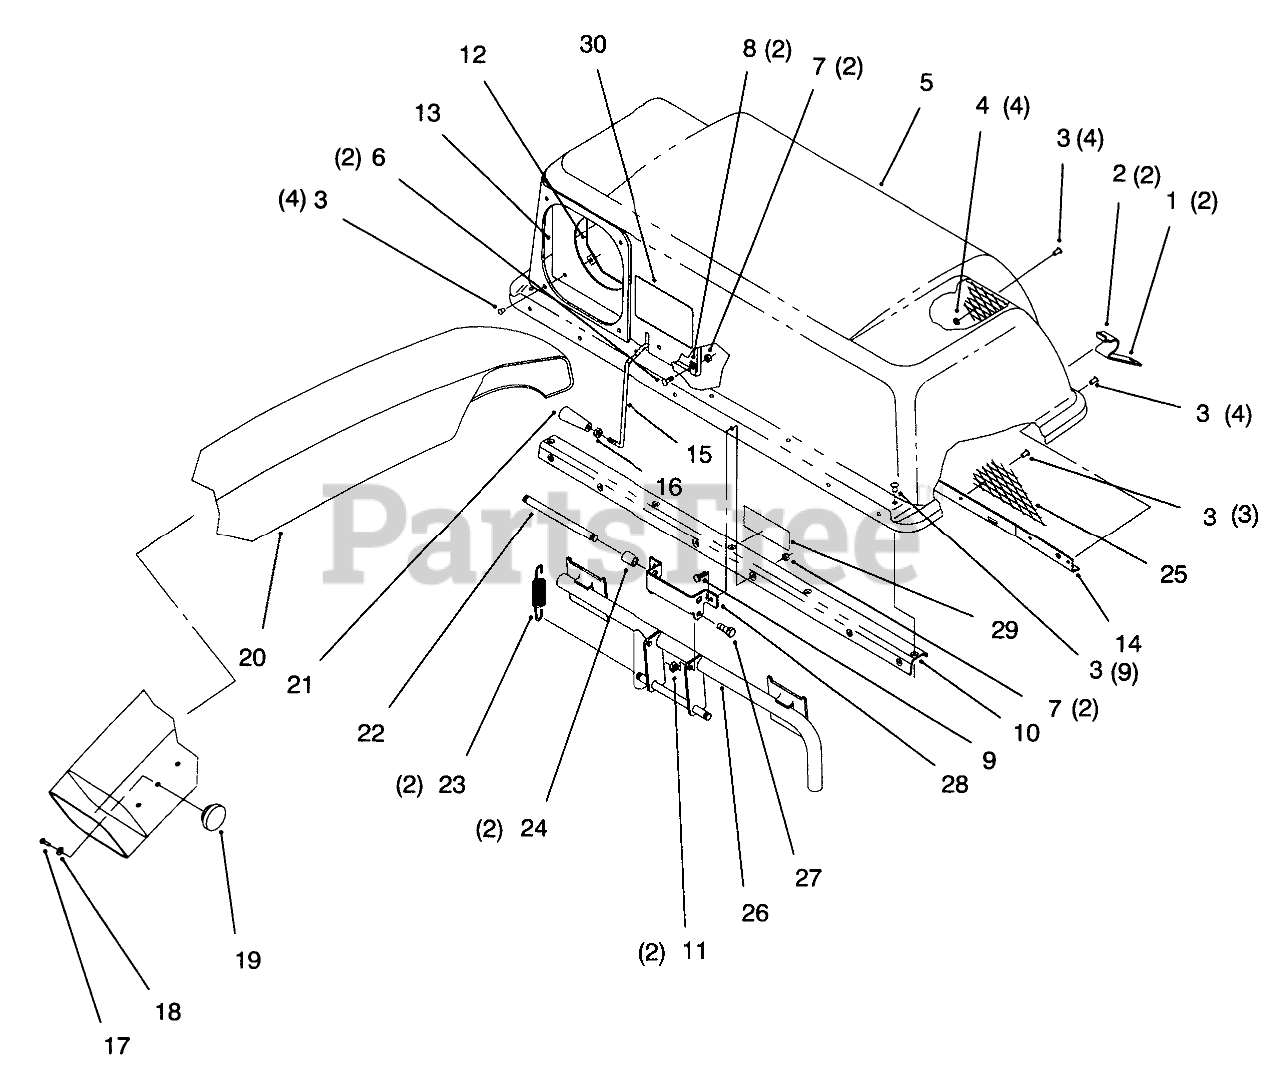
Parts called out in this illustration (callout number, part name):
2	Latch-Bag
3	RIVET-BLIND
4	WASHER-FLAT
5	TOP-BAGGER
6	SCREW-HH
7	NUT-LOCK, NI
8	CLAMP
9	SCREW-HH
10	ASM-Stiffener (Incl. Ref. #29)
11	NUT-LOCK, NI
12	CLAMP-SEAL
13	SEAL-CHUTE
14	Screen Support
15	FEELER-FILL, BAG
16	NUT-JAM
17	SCREW-PPHTF
18	WASHER-PLAIN
20	CHUTE-DISCHARGE
21	HANDLE-TAPERED
22	PIN-SPRING
23	SPRING-EXTENSION
24	Spacer
25	SCREEN-BAGGER
26	FRAME ASM
27	SCREW-HH
28	HINGE-BAG TOPB
29	DECAL-CAUTION
30	DECAL
